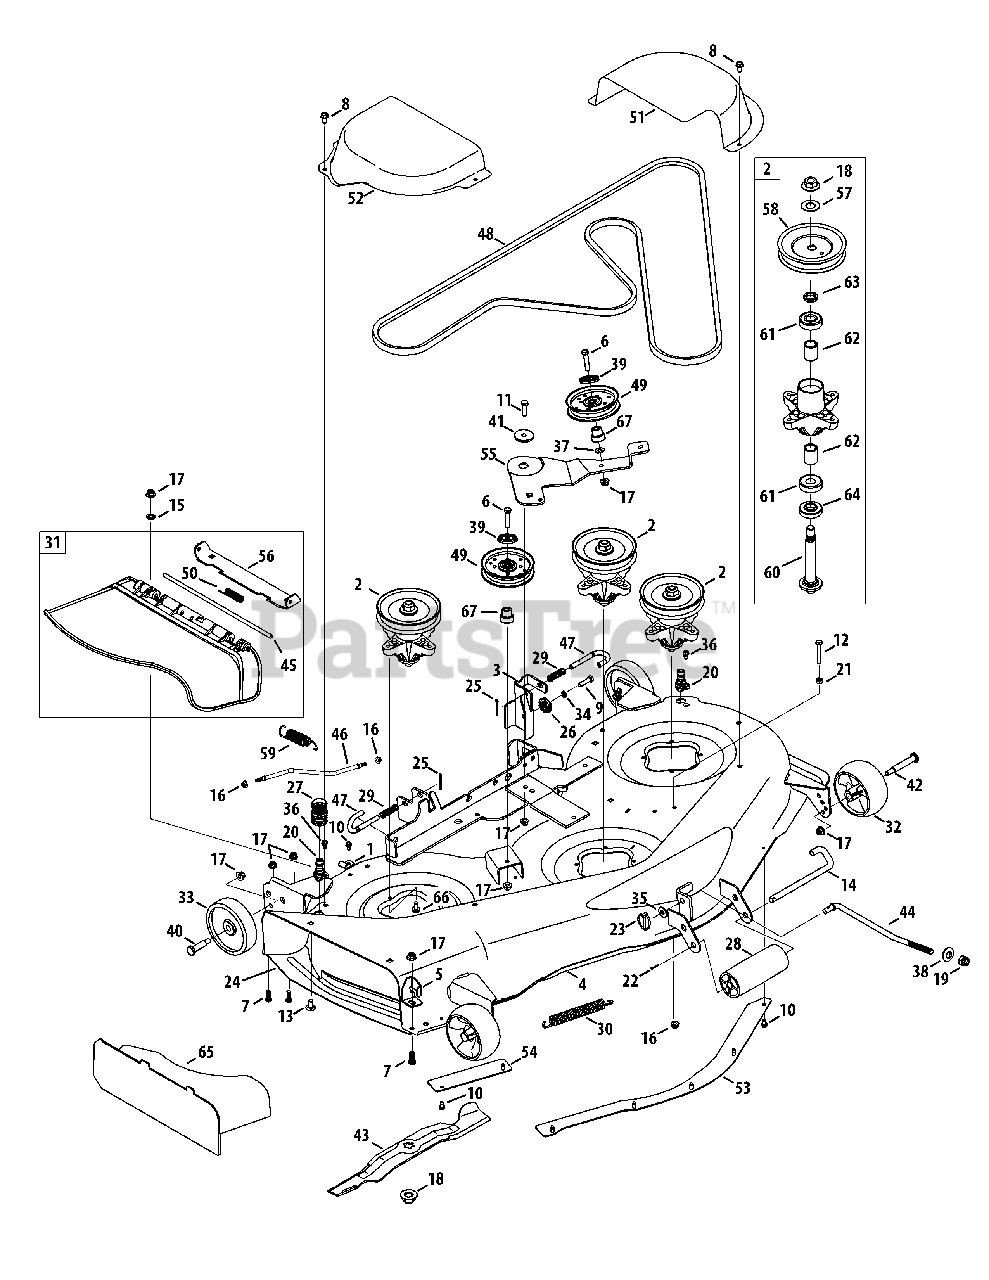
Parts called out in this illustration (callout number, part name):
1	Retainer Hook Brkt.
2	Spindle Assembly
3	Deck Hanger Bracket Ass'y
6	Hex Screw 3/8-16 x 1.75
7	Screw, 3/8-16 x 1.0
8	SCREW 5/16-18 x .750
9	Hex Bolt 5/16-18 x 1.25
10	Hex Wash S-Tapp Scr 1/4-20 x .50
11	Hex Bolt 3/8-16 x 1.25
12	Hex Hd Cap Scr. 5/16-18 x 2.0 Gr. 5
13	CARRIAGE BOLT 3/8-16 x .75
14	Roller Pin
15	Push Nut 3/8
16	Flange Locknut 5/16-18 Gr. F, Nylon
17	Flange Lock-Nut 3/8-16 Gr. F Nylon
18	HEX NUT
19	Flexlock Nut 1/2-13
20	Deck Water Nozzle
21	Hex Nut 5/16-18 hd. (Gr. t5)
22	Cotter Pin 3/32 x 1.0
23	Lynch Pin, .1875
24	Finger Guard
25	Cotter Pin 1/8" Dia x 1.25
26	Deck Adjustment Gear
27	Water Nozzle Adaptor
28	Front Roller
29	Compression Spring .535 OD x 1.75" Lg.
30	Extension Spring .94 x 6.74
31	Chute Ass'y
32	Deck Wheel 5.0
33	PLASTIC WHEEL 5X1.38
34	L-Wash 5/16 ID
35	Flat Washer .531 ID x 1.25 OD x .100
36	Shoulder Screw 1/4-20 x 0.50
37	Flat Washer .406 ID x .875 OD x .059
38	Cupped Washer .63 x 1.25 x .18
39	Pulley Cap
40	Shoulder Bolt .498 Dia x 1.53 x 3/8-16
41	Spacer, Shoulder .884 x .190
42	Shoulder Screw
43	Blade 17.90
44	Front Deck Lift Rod
45	Hinge Pin .3125 x 7.96
46	Deck Sway Rod
47	Deck Release Pin
48	V-Belt
49	Idler Pulley
50	Torsion Spring
51	LH Belt Cover
52	RH Belt Cover
53	Deck Skirt Center
54	Deck Shirt RH
55	Idler Bracket
56	Chute Bracket
57	Flat Washer .760 ID x 1.50 OD x .120
58	Deck Pulley
59	Extension Spring 1.15 OD x 5.99
60	Spindle Shaft
61	Ball Bearing 20 x 47 x 14:6204:DS
62	Spacer .800 x 1.10 x 1.322
63	Spacer .790 x 1.25 x 1.75
64	Spacer .79 x 1.82 x .55
65	Mulching Plug
66	Hex. TT Screw 5/16-18 x .75
67	Idler ShoulderSpacer
